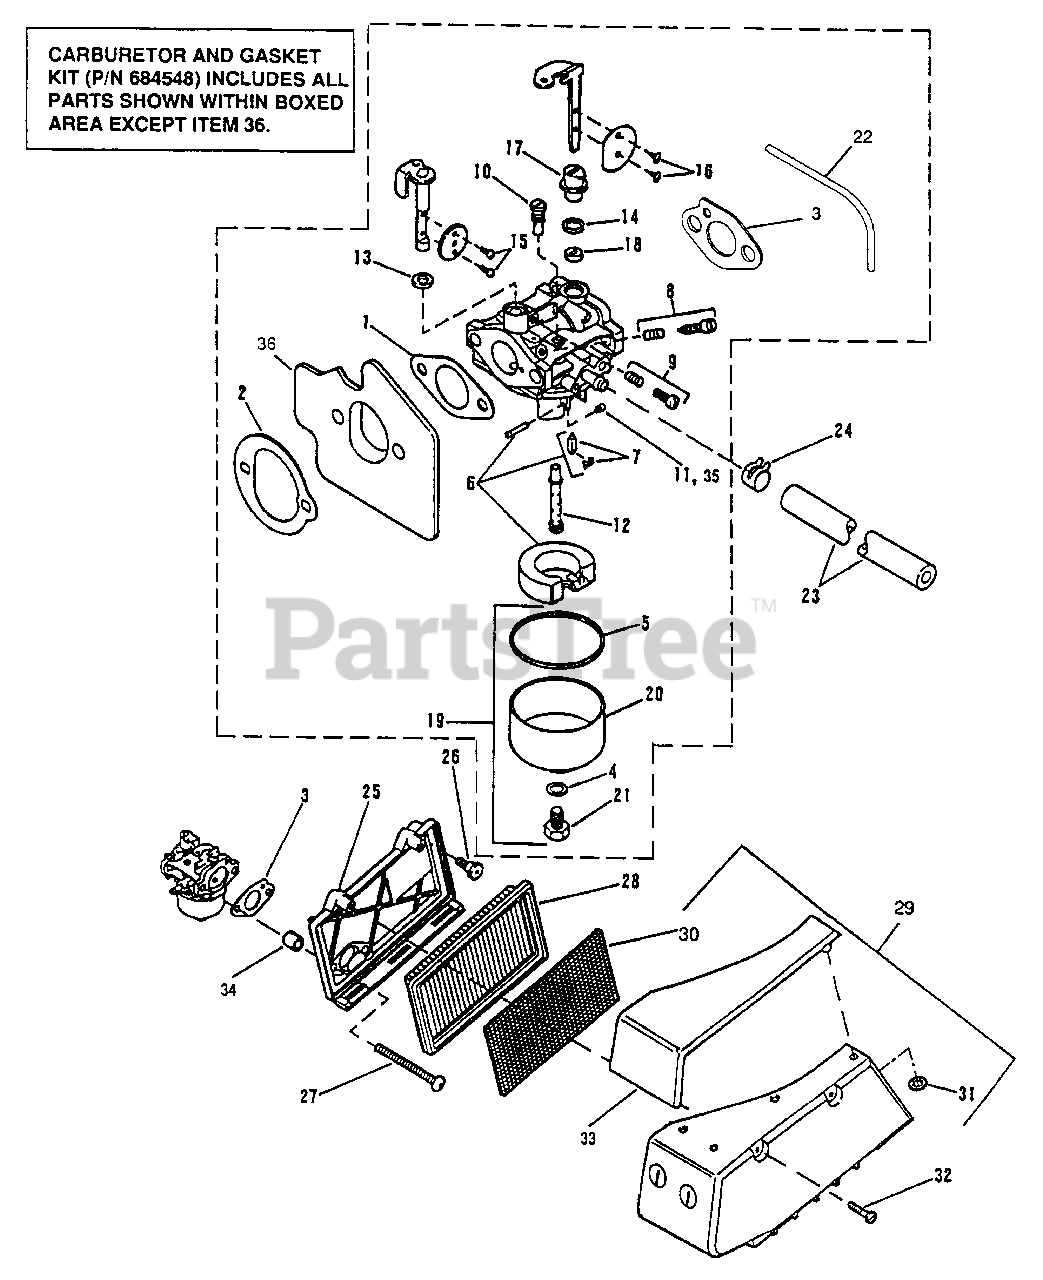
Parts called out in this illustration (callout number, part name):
1	Gasket-Carburetor to Spacer
2	Gasket-Spacer to Engine
3	Gasket-Air Filter Base
4	Gasket-Bowl Retainer
5	Gasket-Fuel Bowl
6	Float & Needle Kit (Inc. 7)
7	Needle and Clip
8	Idle Needle & Spring Kit
9	Idle Speed Kit
10	Pilot Jet
11	Main Jet
12	Nozzle
13	Throttle Shaft Seal
14	Choke Shaft Seal
15	Screw-Throttle Valve
16	Screw-Choke Valve
17	Upper Choke Shaft Pivot
18	Lower Choke Shaft Pivot
19	Bowl Kit (Inc. 20-21)
20	Fuel Bowl
21	Screw-Bowl Retainer
22	Hose-Carb Vent
23	Gas Line
24	Hose Clamp
25	Air Filter Base
26	Bolt
27	Screw-Carburetor to Engine
28	Air Filter
29	Air Filter Cover Assy (Inc. 30-33)
30	Pre-Filter
31	Pushnut
32	Screw
33	Air Box Cover
34	Spacer
35	Main Jet-High Altitude
36	Spacer & Oil Nozzle Assy
